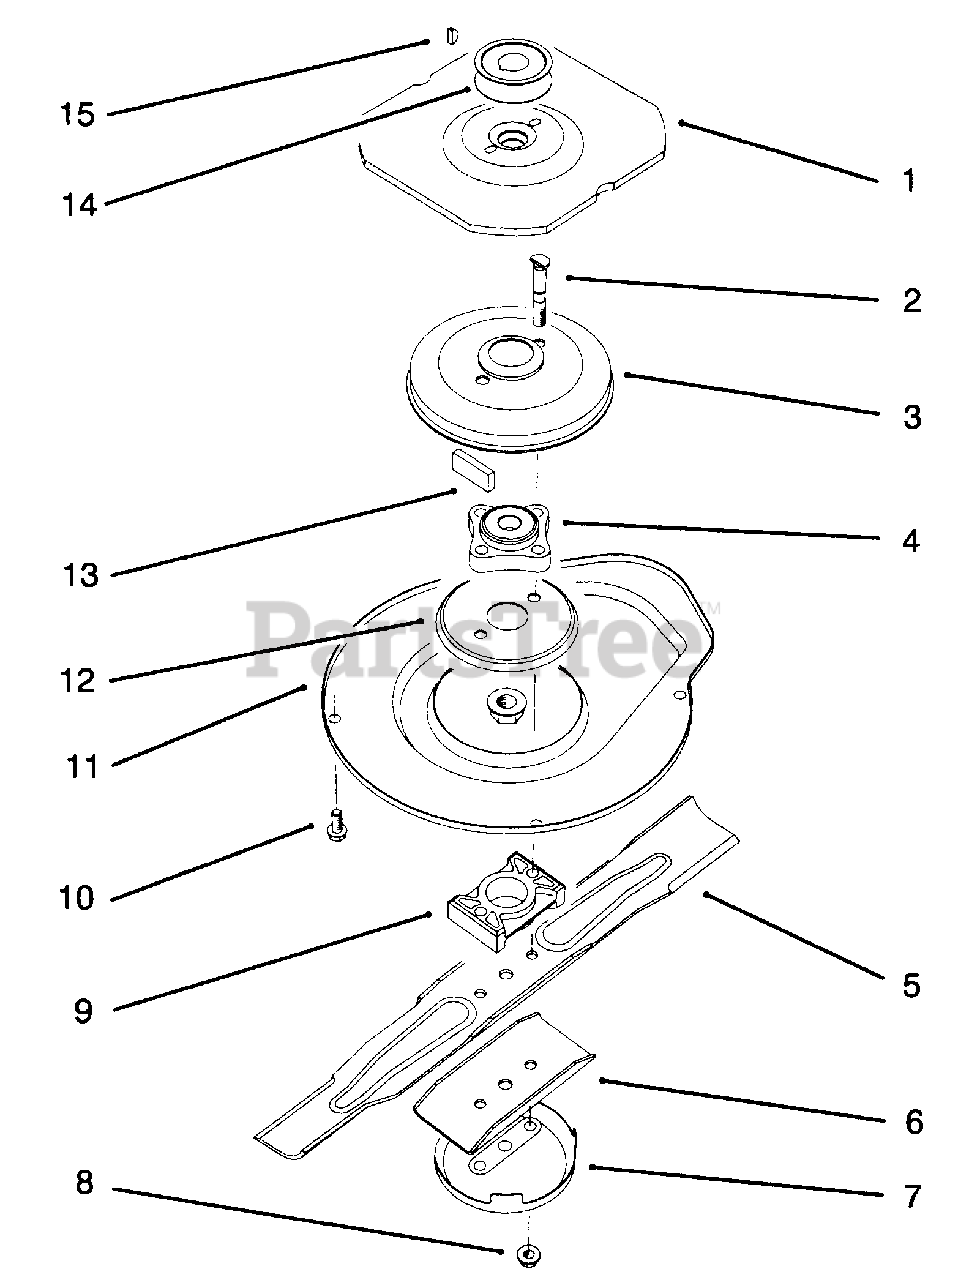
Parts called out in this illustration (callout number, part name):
1	Flywheel-BBC
2	Bolt-Blade
3	Drum-Brake
5	Blade-21"
6	Stiffener-Blade
7	Cup-Anti Scalp
8	Nut-Lock
9	Spacer-Blade
10	Screw-Tapping
11	Shield-BBC
12	Screen-BBC
13	Damper-Vibration
14	Pulley-Driver
15	Key-Woodruff
